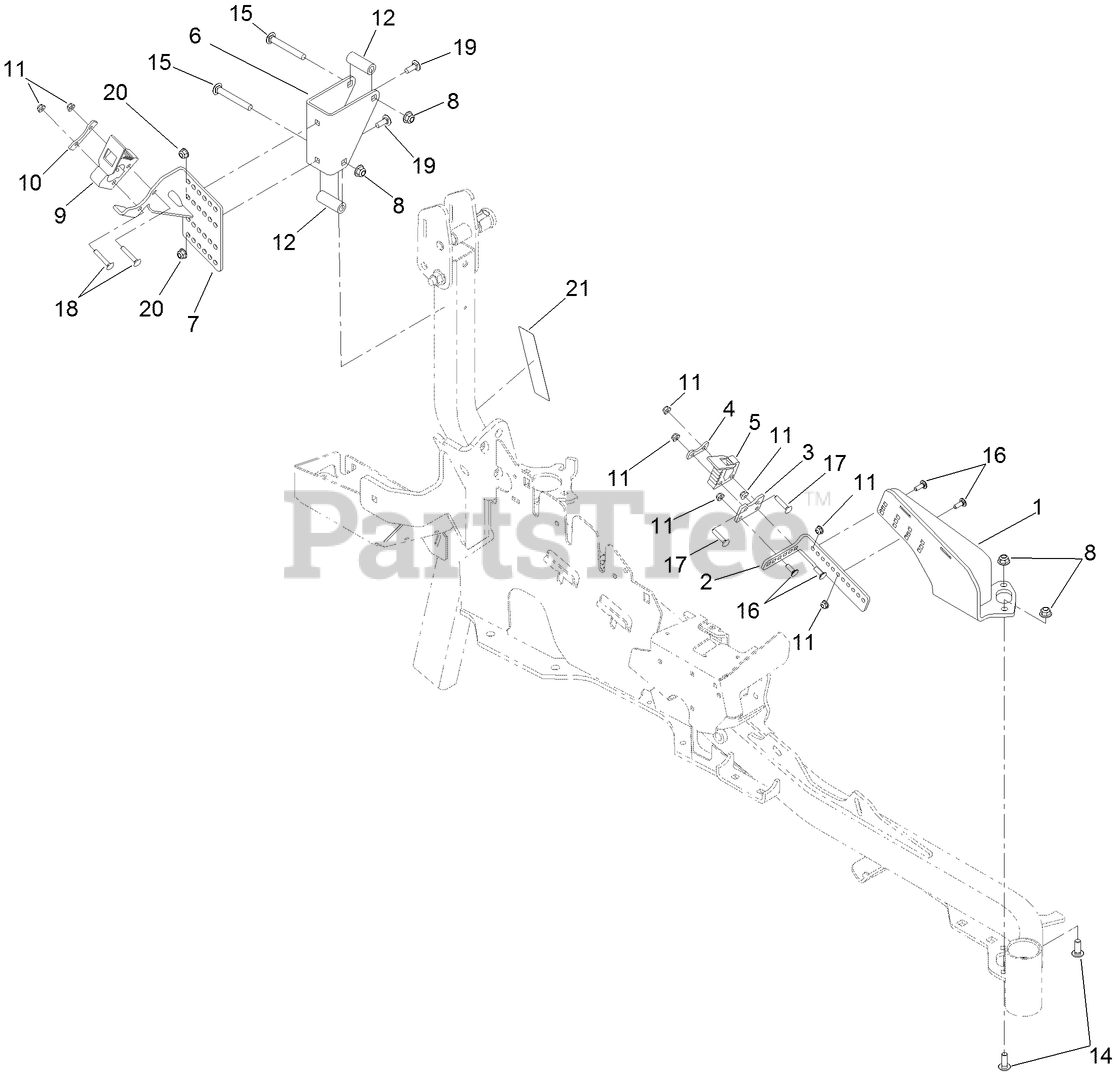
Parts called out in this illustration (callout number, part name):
1	MOUNT-TIRMMER, LOWER
2	BRACKET-MOUNT, TRIMMER
3	PLATE-MOUNT, QUICK FIST
4	PLATE-BACKER, SMALL
5	CLAMP-QUICK FIST, MINI
6	BRACKET-SUPPORT
7	BRACKET-MOUNT, UPPER TRIMMER
8	NUT-HF, NI
9	CLAMP-QUICK FIST, ORIGINAL
10	PLATE-BACKER, LARGE
11	NUT-HF
12	SPACER-TUBE
14	SCREW-CARR
15	SCREW-CARR
16	BOLT-CARR
17	SCREW-CARR
18	SCREW-CARR
19	BOLT-CARR
20	NUT-HF, NI
21	DECAL-CAUTION, FUEL VENT
